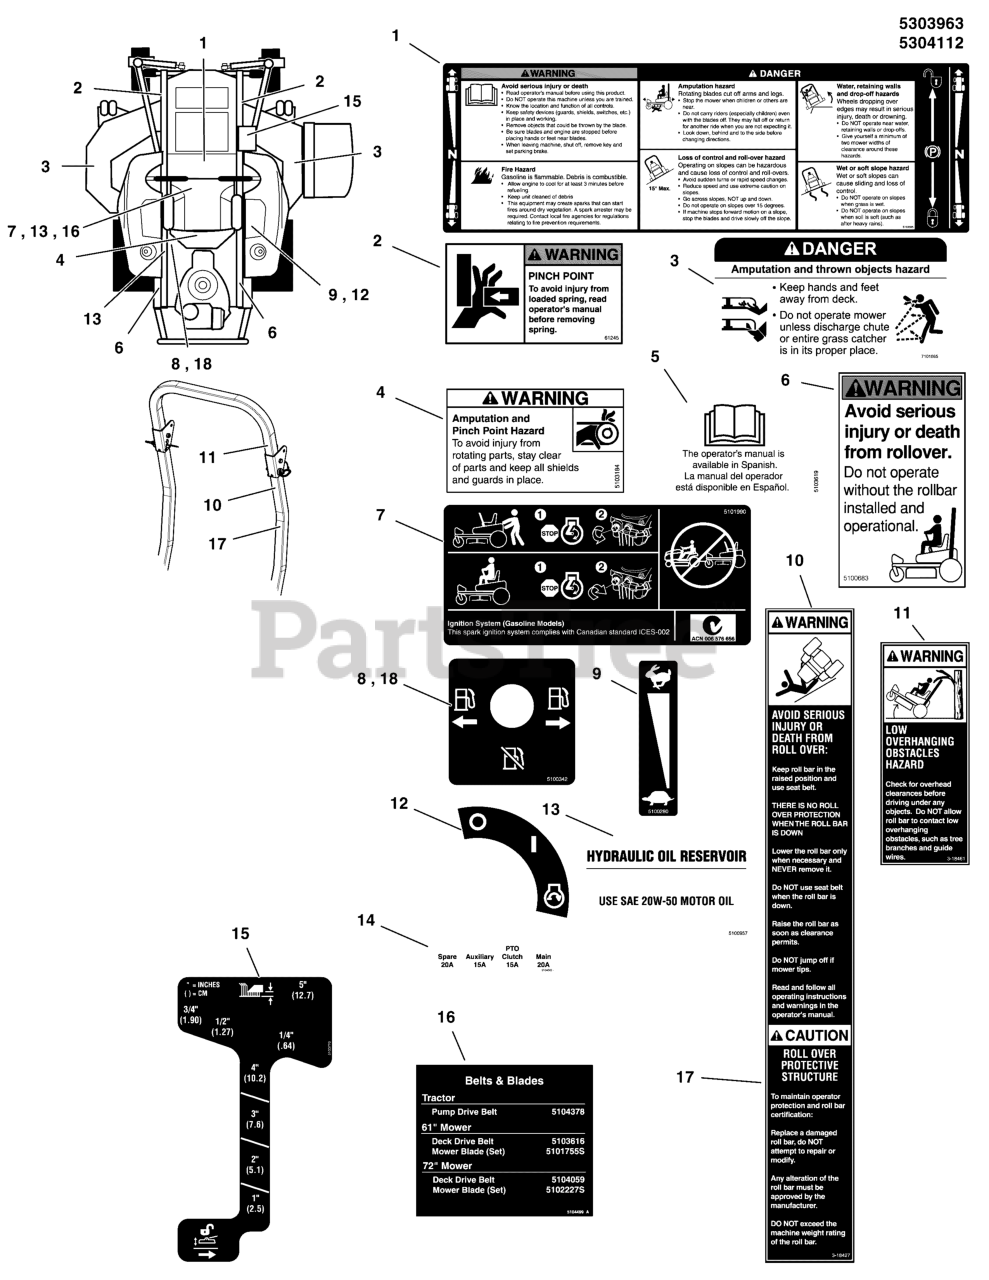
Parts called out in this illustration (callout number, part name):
1	DECAL, MAIN SAFETY
2	DECAL, PINCH POINT
3	DECAL, DANGER DO NOT OPERATE W/O DEFLECT
4	DECAL, WARNING, HAND IN BELT, ENG ONLY
5	DECAL, MANUAL AVAIL IN SPANISH
6	DECAL, WARNING, ROLL BAR
7	DECAL, TRANSAXLE RELEASE, S200XT
8	DECAL, FUEL VALVE
9	DECAL, THROTTLE CONTROL
10	DECAL, WARNING, FOLDING ROPS
11	DECAL, WARNING, OVERHAND, ROPS
12	DECAL, IGNITION SWITCH
13	DECAL, HYDRAULIC OIL, SAE 20W50
14	DECAL, FUSE LOCATION, IS2100
15	DECAL, CUT HEIGHT, IS700/ZTS700
16	DECAL, BELT AND BLADE, IS3200Z
17	DECAL, CAUTION, FOLDING ROPS
18	DECAL, FUEL VALVE
